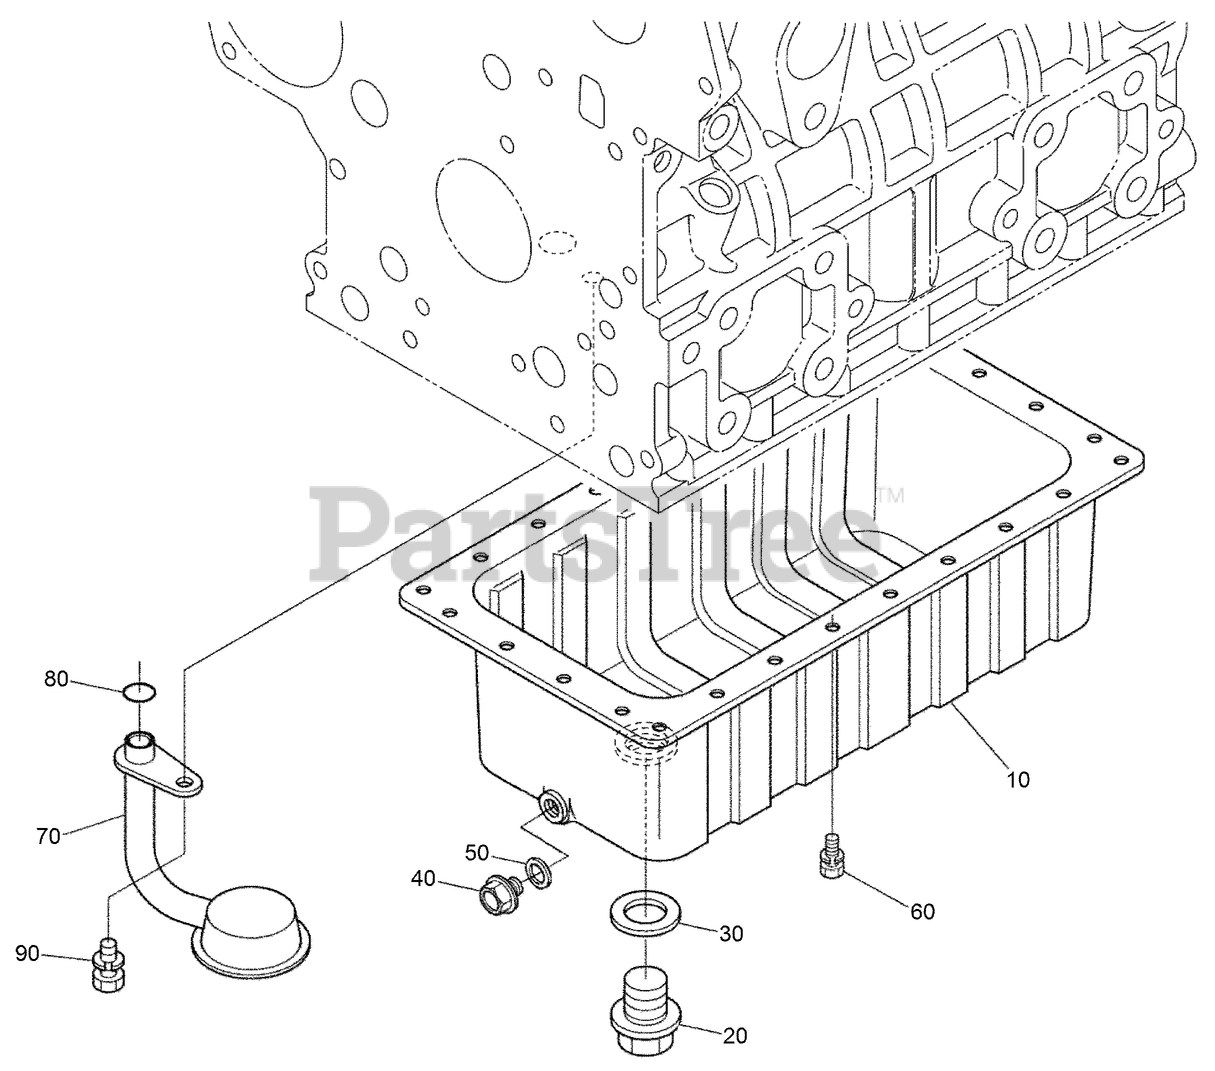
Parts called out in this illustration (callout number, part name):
10	OIL PAN ASM
20	PLUG-DRAIN
30	GASKET-PAN, OIL
40	PLUG-DRAIN
50	GASKET
70	SCREEN-FILTER, OIL
80	O-RING
